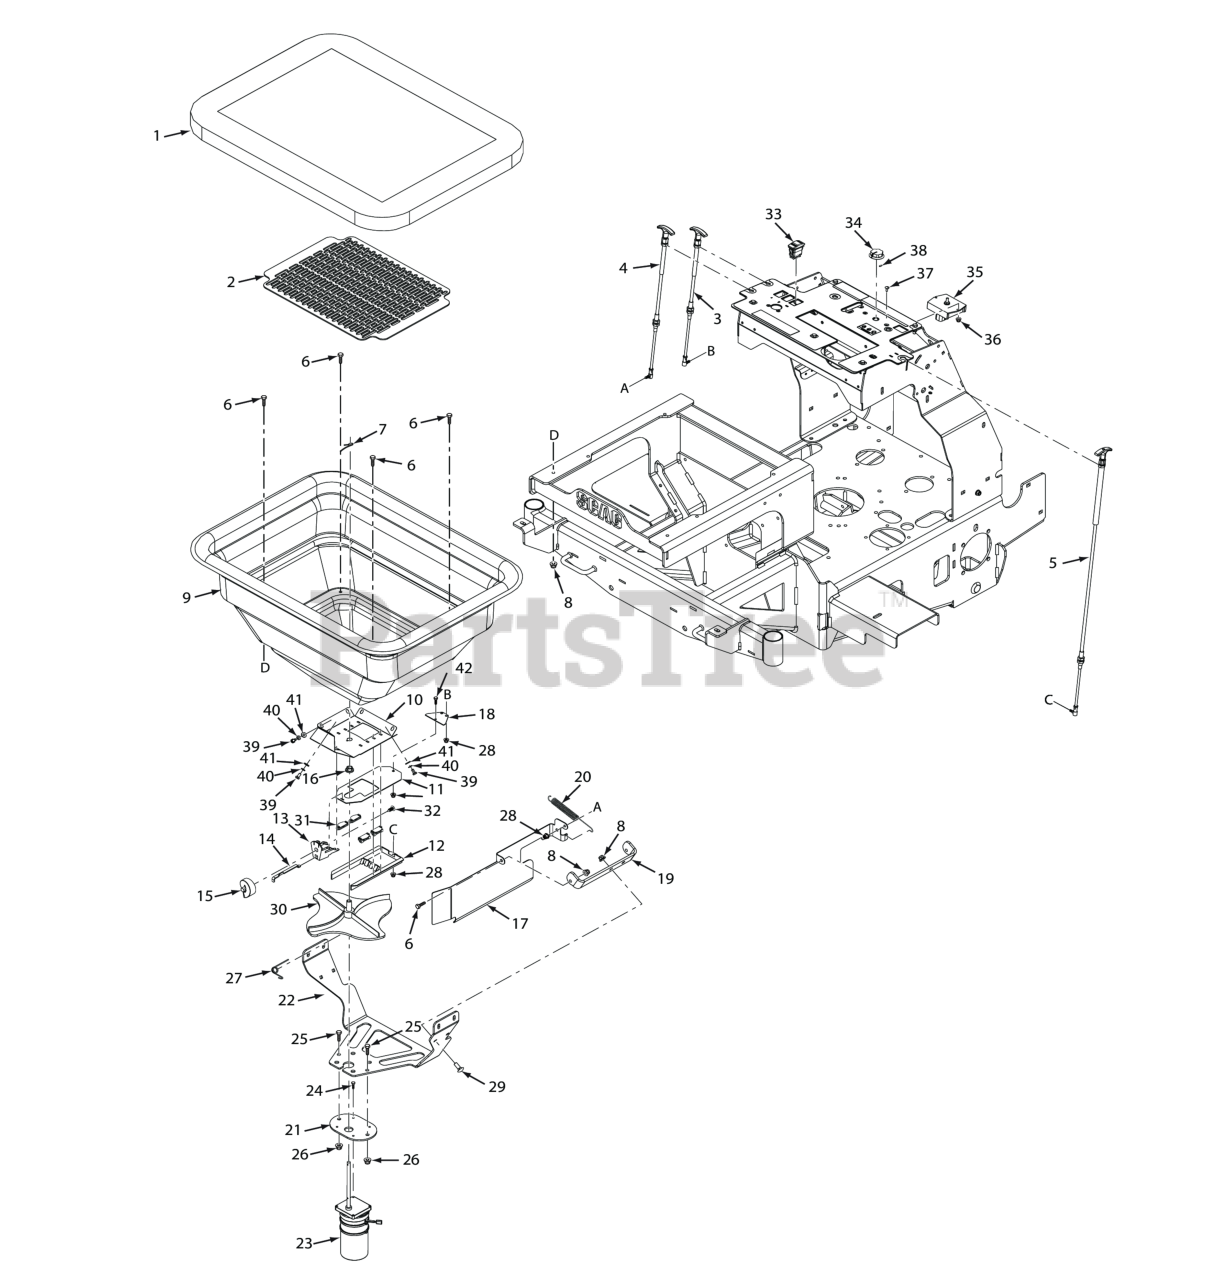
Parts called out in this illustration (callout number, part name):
1	Cover, 220lb Hopper
2	Grate, Spreader
3	Cable, Hopper Gate
4	Cable, Side Deflector
5	Cable, Pattern Adjust
6	Bolt, Hex 5/16" - .375 x 1.00- Stainless Steel
7	Agitator
8	Locknut, 5/16-18 Flg. Elastic Stop - Stainless Steel
9	Hopper Assembly
10	Mounting Plate, Speader System
11	Gate, Rear
12	Diffuser
13	Mount, Dial
14	Linkage, Rate Gate
15	Milled Dial
16	Bearing, Hopper Bottom
17	Guard Door, LH Hopper
18	Door Arm
19	Mounting Bracket, Deflector Door
20	Spring, Door Assist
21	Mounting Plate, Electric Motor
22	Motor Mount Bracket
23	Gear Motor, Electric
24	Bolt, Hex #10-32 x .50 - Stainless Steel
25	Bolt, Hex 3/8 - 16 x 1.00 - Stainless Steel
26	Nut, Flange Elastic Stop 3/8 - 16 - Stainless Steel
27	Spring, SS Clip
28	Nut, 1/4-28 Elastis Stop - Stainless Steel
29	Bolt, Carriage 5/16 - 18 x 1" - - Stainless Steel
30	Impeller
31	Guide, Rate Gate
32	Linkage, Rate Gate
33	Switch, Rocker
34	Knob (Incl #38)
35	Motor Controller
36	Locknut, #10 - 32 Elastic Stop - Stainless Steel
37	Bolt, Carriage #10 - 32 x .50 - Stainless Steel
38	Set Screw, #8 - 32 x .375
39	Bolt, Hex Head 1/4 - 20 x .50 - Stainless Steel
40	Washer, Lock 1/4 Spring - Stainless Steel
41	Washer, Flat 1/4-.281X.625X.080 - Stainless Steel
42	Bolt, Hex Head #10 - 32 x 3/4" - Stainless Steel
